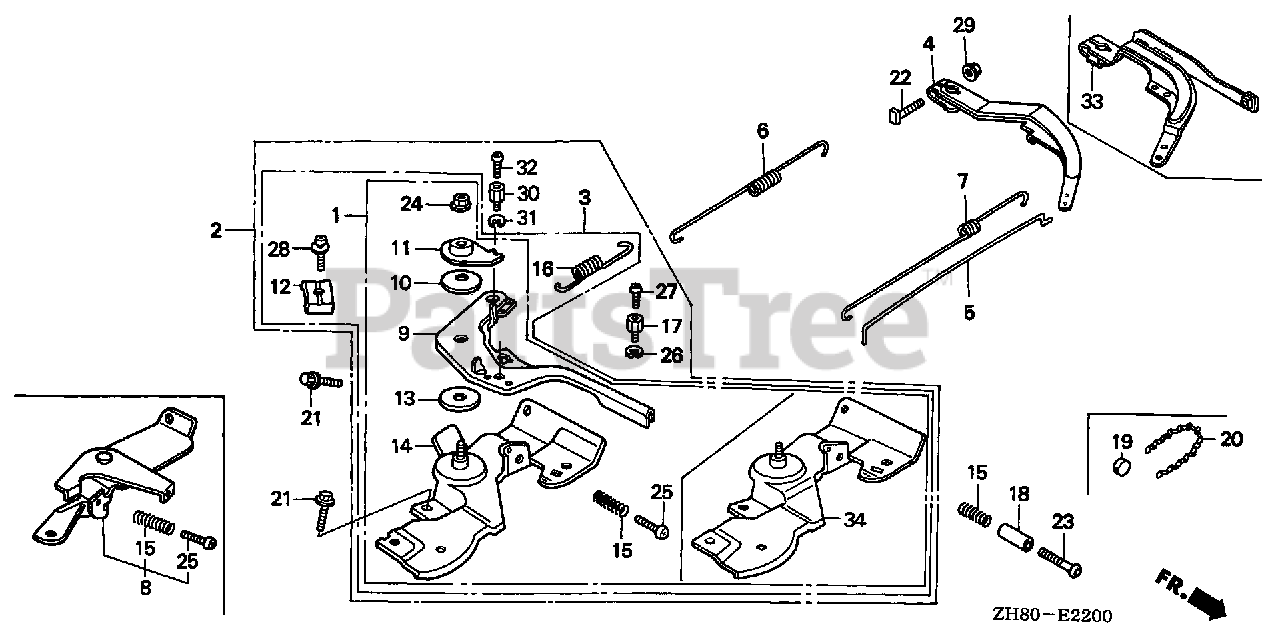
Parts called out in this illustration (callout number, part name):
2	CONTROL ASSY. (REMOTE/INTERNAL)
4	ARM, GOVERNOR
5	ROD, GOVERNOR
6	SPRING, GOVERNOR
7	SPRING, THROTTLE RETURN
9	LEVER, CONTROL
10	SPRING, LEVER
11	WASHER, CONTROL LEVER
12	HOLDER, CABLE
13	SPACER, CONTROL LEVER
14	BASE, CONTROL (REMOTE)
15	SPRING, CONTROL ADJUSTING
16	SPRING, CABLE RETURN
17	HOLDER, WIRE
21	BOLT, FLANGE (6X12) (CT200)
22	BOLT, GOVERNOR ARM
24	NUT, SELF-LOCK (6MM)
25	SCREW, PAN (5X20)
25	SCREW, PAN (5X25)
26	CIRCLIP (5MM)
27	SCREW, PAN (4X6)
28	SCREW, PAN (5X16)
28	SCREW-WASHER (5X16)
29	NUT, FLANGE (6MM)
34	BASE, CONTROL (REMOTE)
